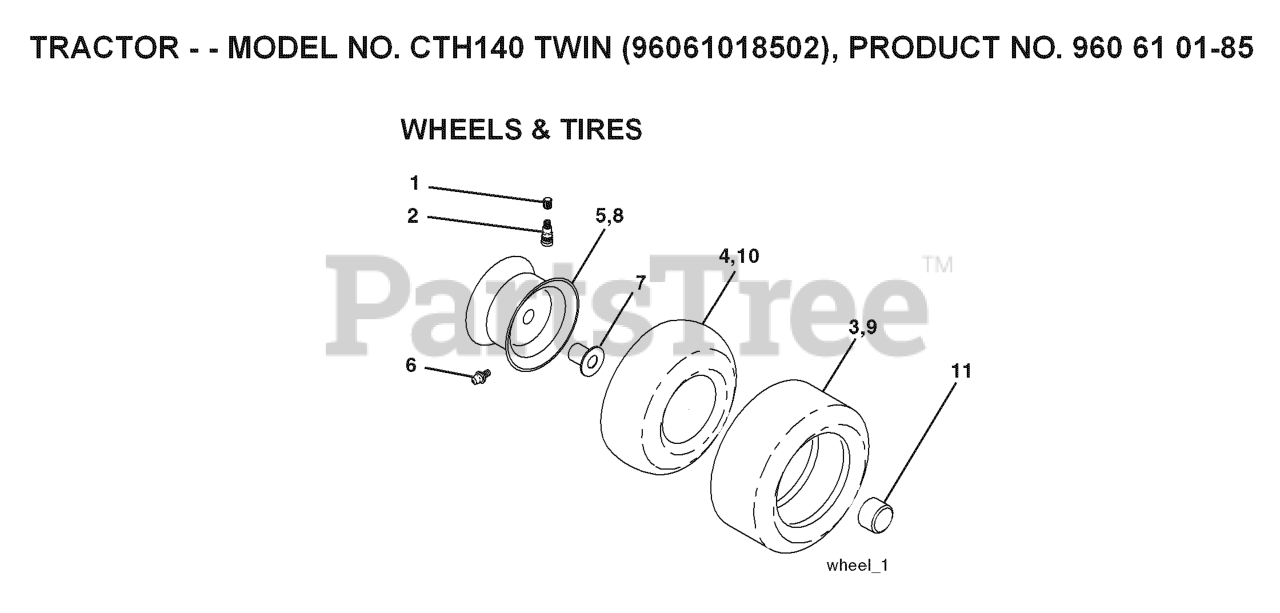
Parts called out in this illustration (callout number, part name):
2	VALVE STEM LT
3	TIRE HEAVY DUTY
4	TUBE.5.3/4.5/6
5	RIM ASM 6" FRONT SILVER
6	FITTING LT
7	BEARING T
8	RIM ASM 8" REAR SILVER
9	TIRE.TS.20X10-8
10	TUBE
11	CAP, AXLE BLK
